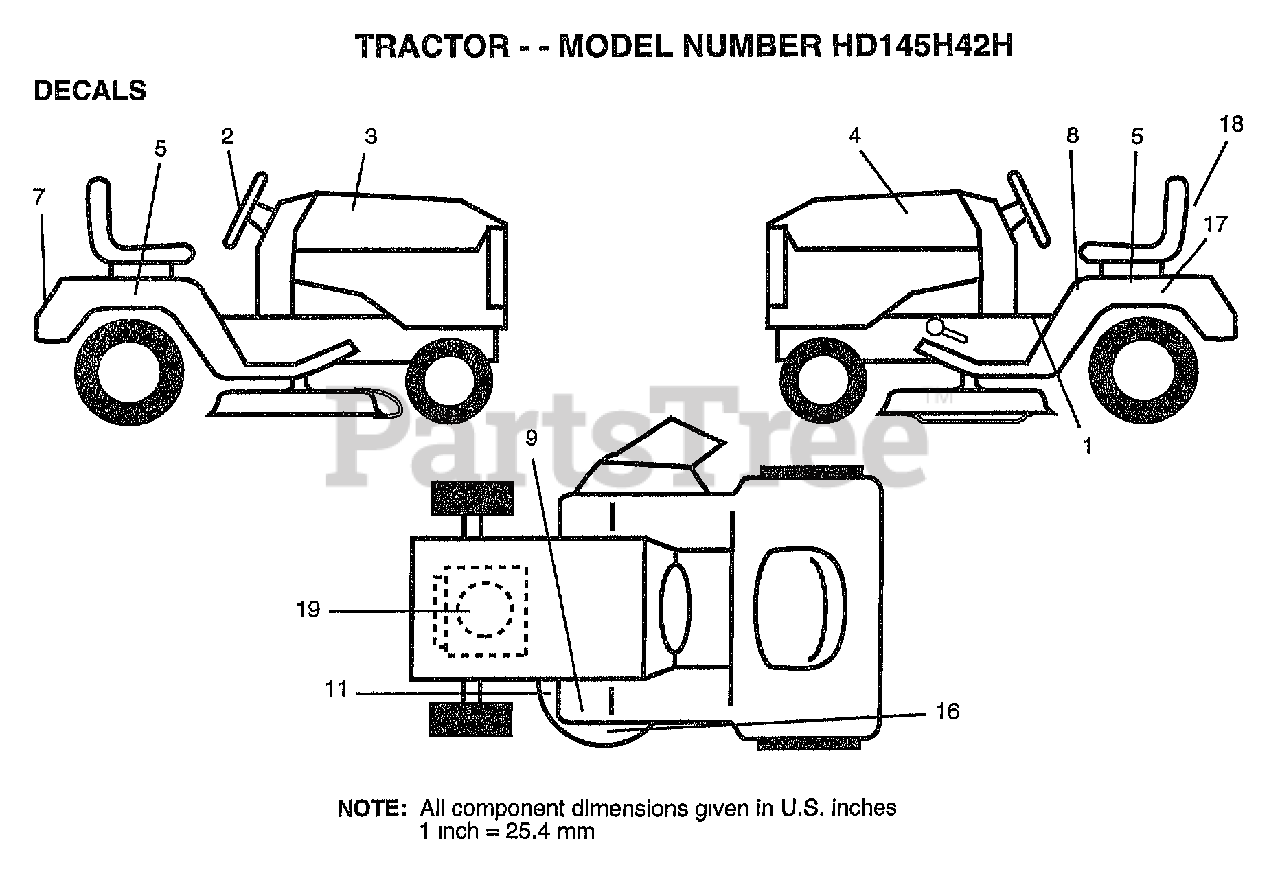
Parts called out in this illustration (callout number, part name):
1	"DECAL-SADDLE,INST"
2	"DECAL WHEEL,STEER"
3	"DECAL-HOOD,RH"
4	"DECAL-HOOD,LH"
5	"DECAL FENDER,SD"
7	"DECAL FENDER,LOGO"
8	"DECAL FENDER,DANG"
9	DECAL CLUT/BRAKE
11	"DECAL-SCHEM,BELT"
17	DECAL.BATRY.3-3908
18	"DECAL SEAT,ACC"
19	"DECAL REPLCMT,ENG"
